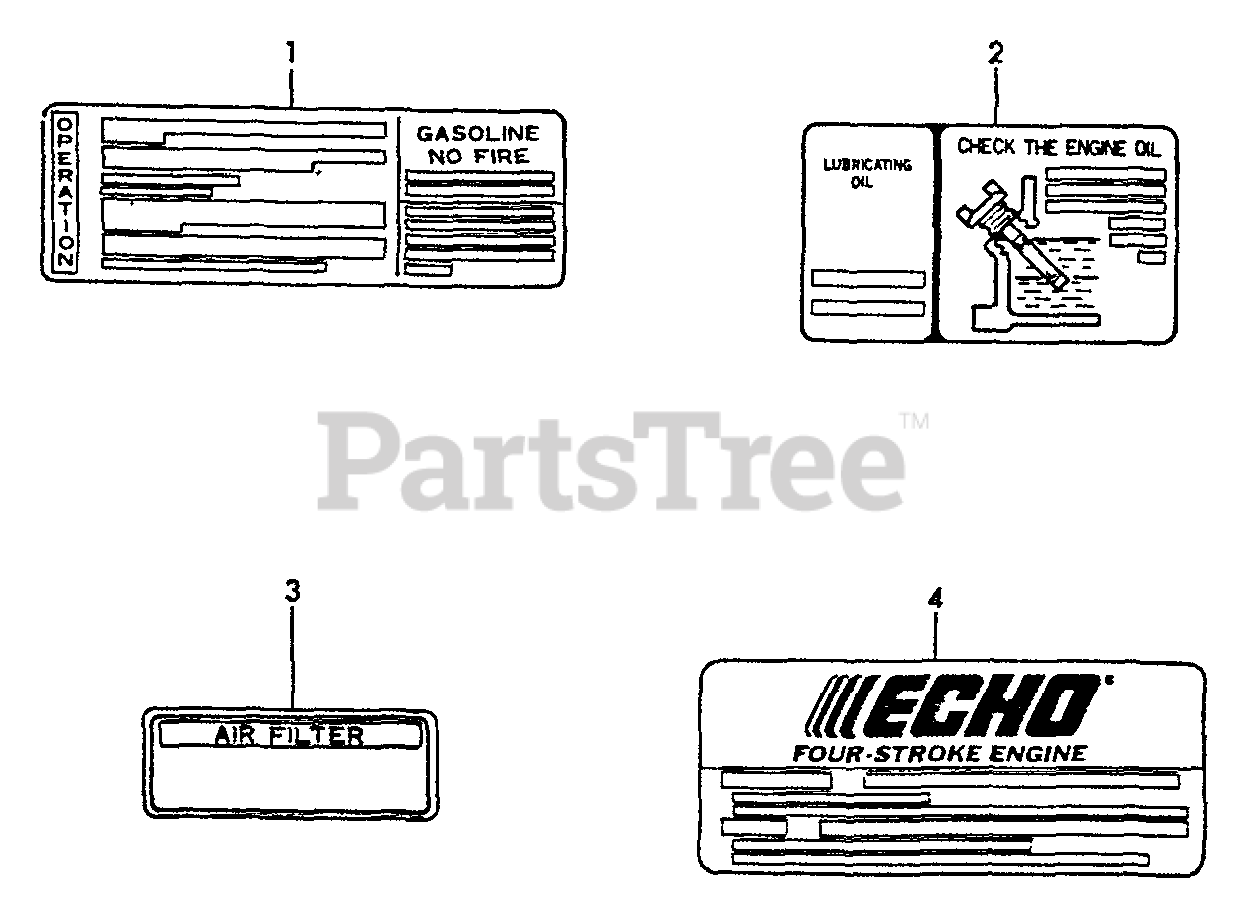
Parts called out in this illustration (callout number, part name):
1	LABEL - OPERATION
2	LABEL - OIL
3	LABEL - AIR CLEANER
4	LABEL - ECHO
